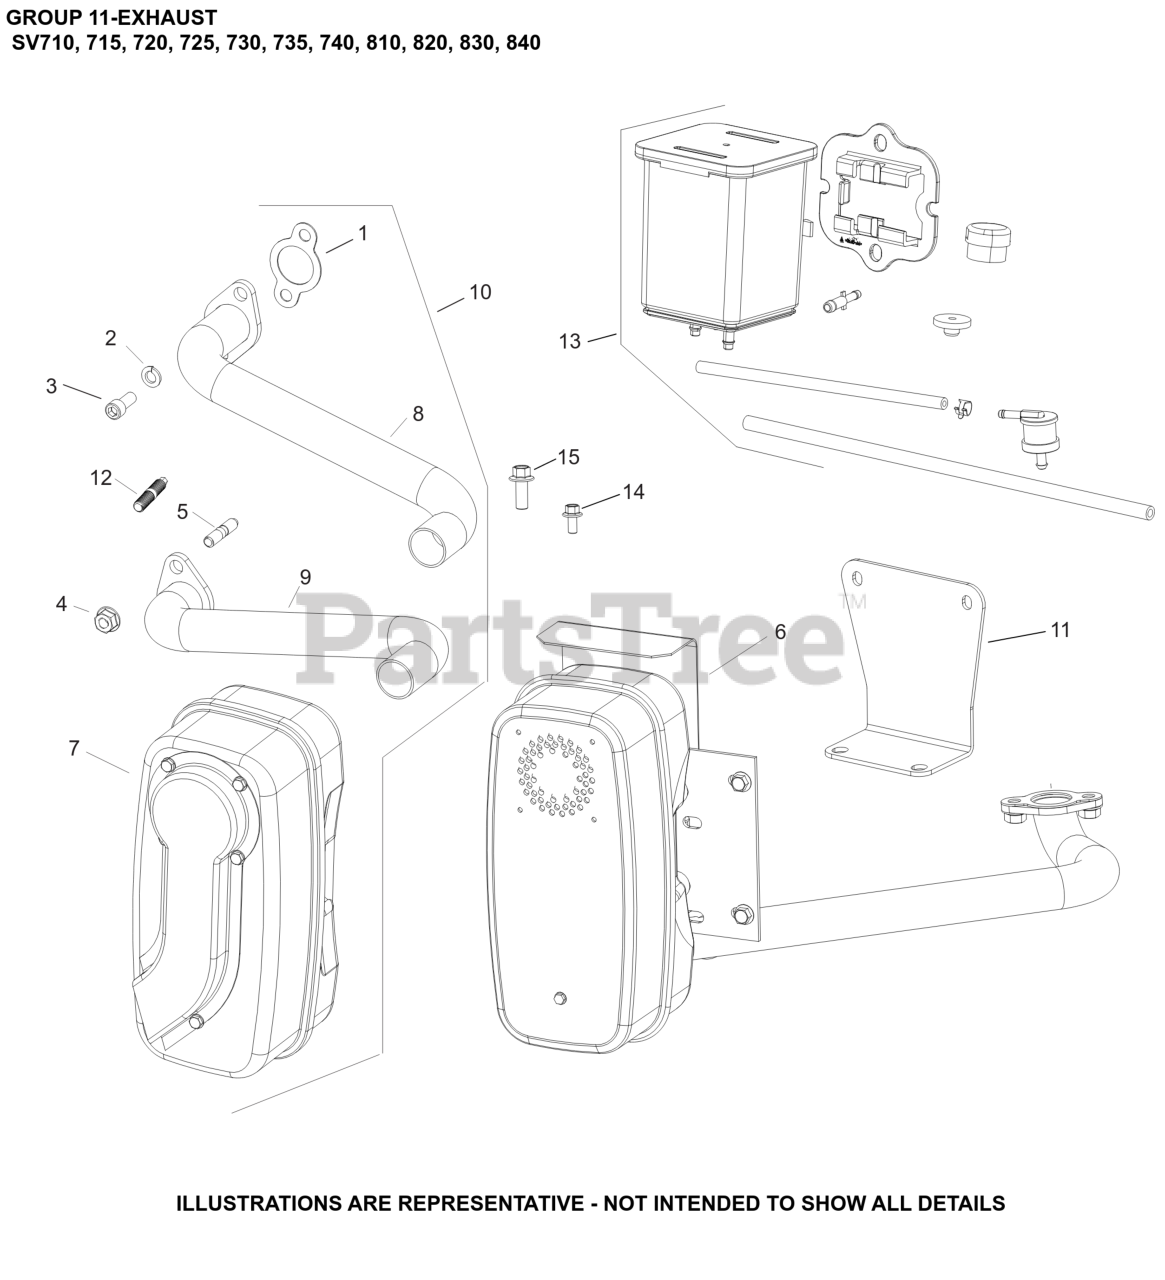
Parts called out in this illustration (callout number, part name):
1	GASKET, EXHAUST
2	WASHER, SPRING LOCK 5/16"
3	SCREW, HEX SOCKET HEAD CAP
